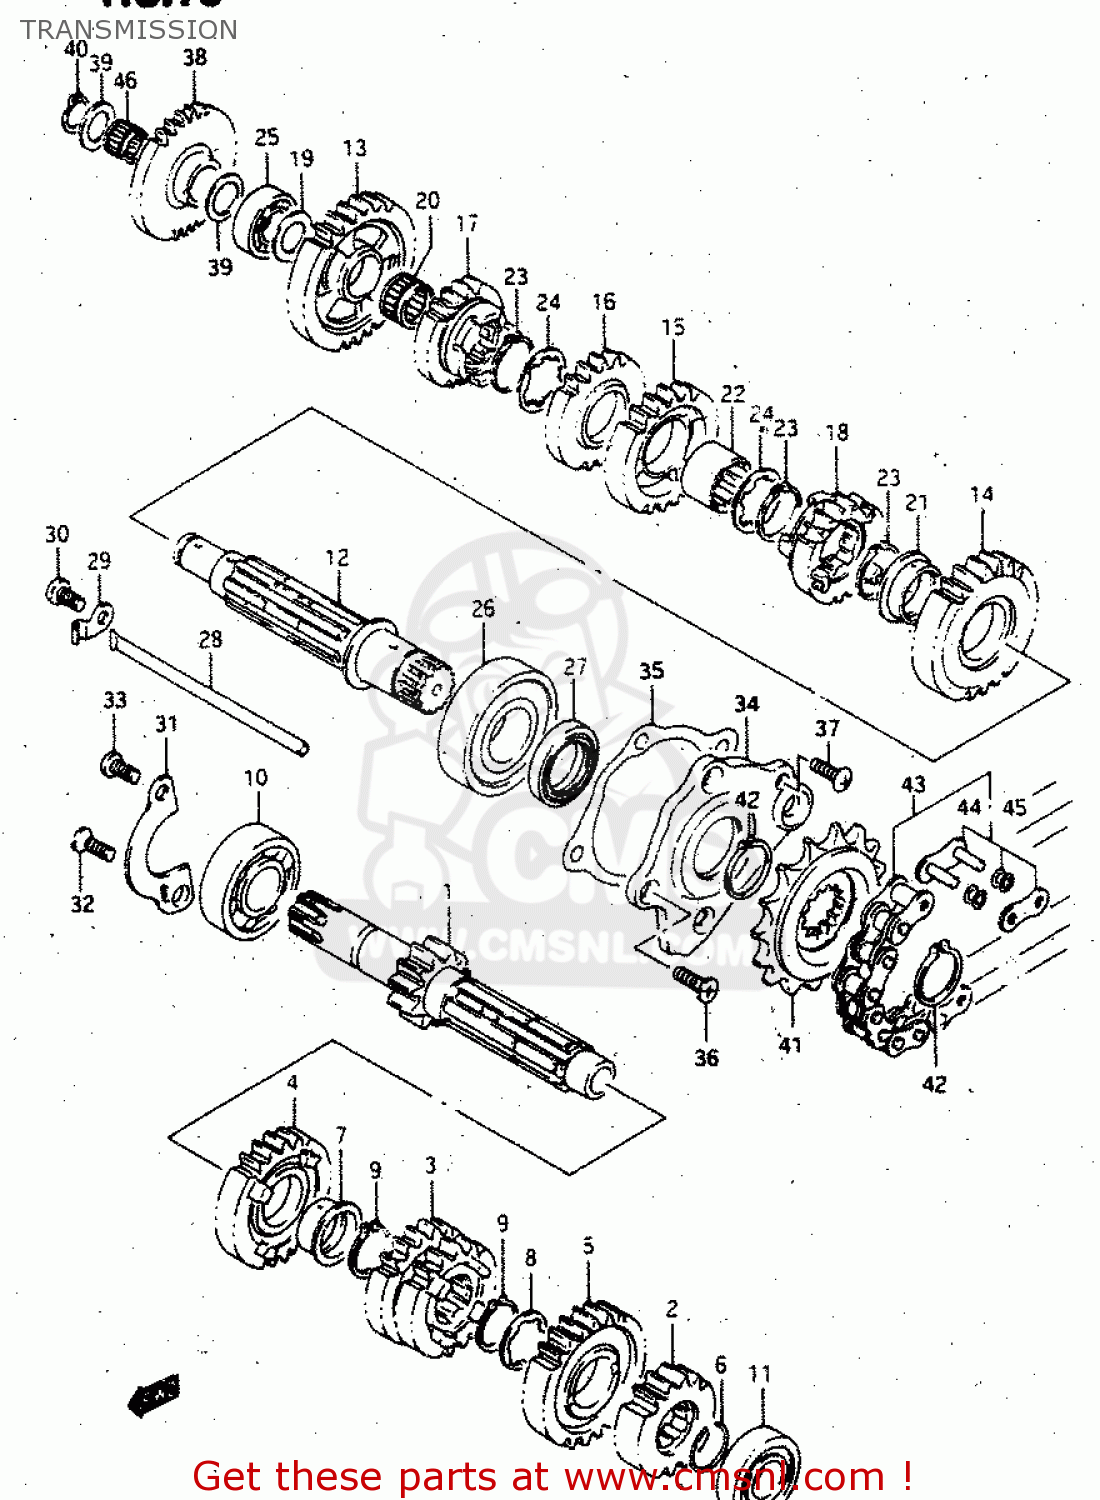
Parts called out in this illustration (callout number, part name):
1	SHAFT,COUNTER(NT:11)
2	GEAR,2ND DRIVE(NT:16)
3	GEAR,3RD & 4TH DRIVE(NT:17/22)
4	GEAR,5TH DRIVE(NT:24)
5	GEAR,6TH DRIVE(NT:25)
6	CIRCLIP
7	BUSH
8	WASHER,LOCK
9	CIRCLIP
10	BEARING
11	BEARING
12	SHAFT,DRIVE
13	GEAR,1ST DRIVEN(NT:27)
14	GEAR,2ND DRIVE
15	GEAR,3RD DRIVEN(NT:21)
16	GEAR,4TH DRIVEN(NT:23)
17	GEAR,5TH DRIVEN(NT:22)
18	GEAR,6TH DRIVEN
19	WASHER
20	BEARING(18X22X12.8)
21	BUSH
22	BUSH,3RD & 4TH DRIVEN GEAR
23	RING,SNAP
24	WASHER,LOCK
25	BEARING, RH
26	BEARING
27	SEAL,OIL(25X38X6)
28	GUIDE,TRANSMISSION OIL
29	RTNR,OIL GUIDE
30	SCREW
31	RETAINER
32	SCREW 6X16
33	SCREW ,6X16
34	RETAINER,DRIVE SHAFT BEARING
35	GASKET,BRG RTNR (NAS)
36	SCREW ,6X16
37	SCREW(6X16)
38	GEAR,KICK IDLE
39	WASHER,THRUST
40	CIRCLIP
41	SPROCKET,ENGINE(NT:14)
42	CIRCLIP
43	CHAIN,DRIVE
44	JOINT,CHAIN
45	JOINT (DID)
46	BEARING(15X19X13)
